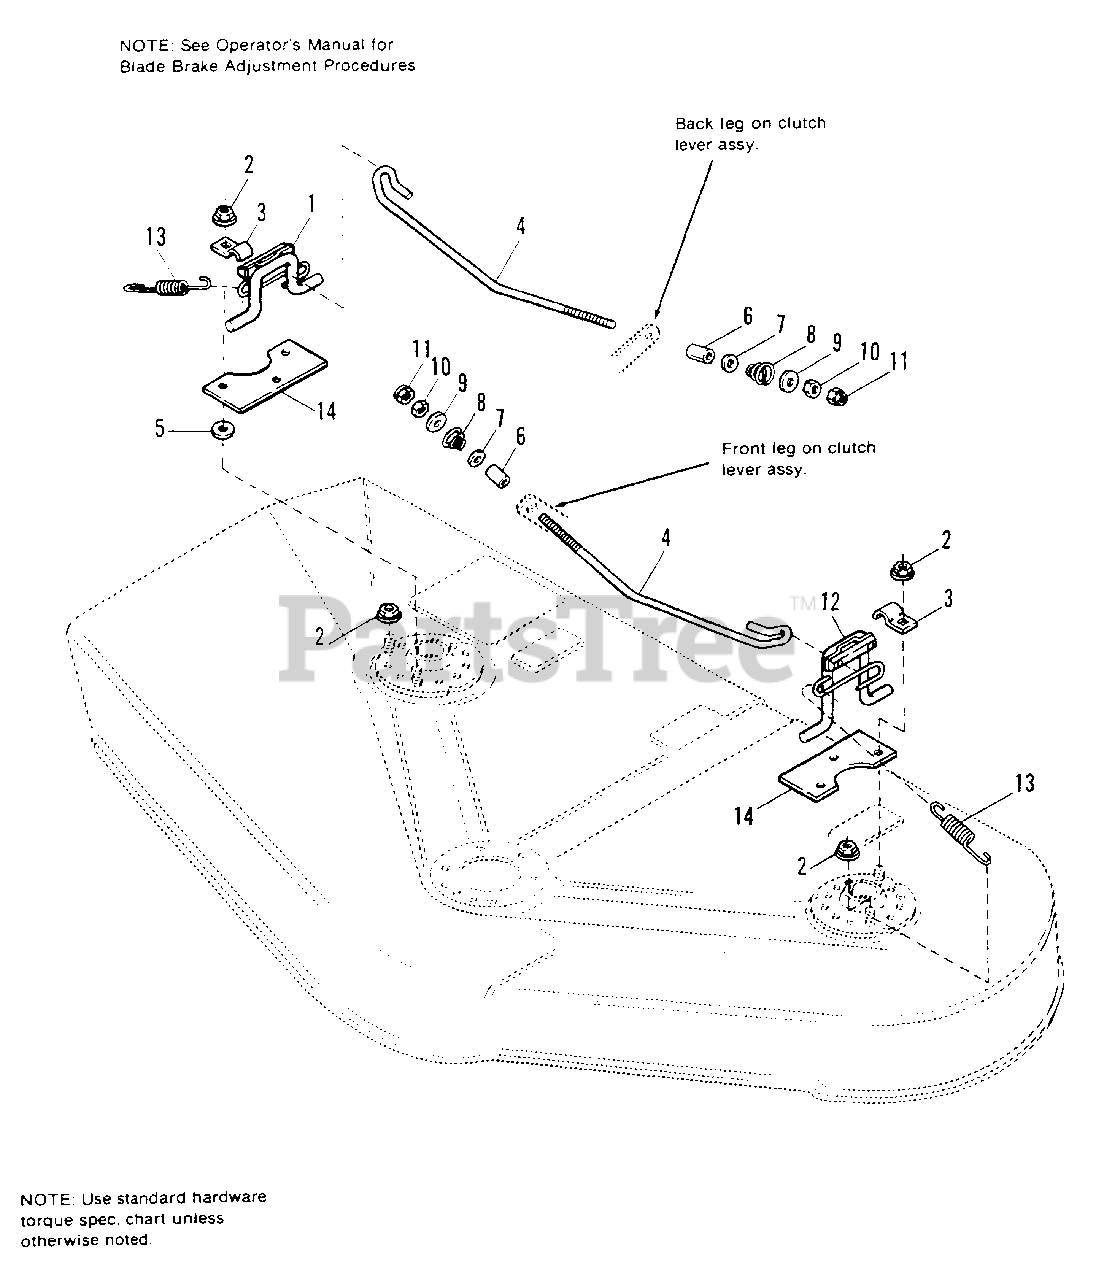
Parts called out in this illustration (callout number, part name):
1	ROD ASSY, Brake, R.H. w/Pad
2	NUT, Hex Flange Lock, 5/16-18
4	ROD Brake 42
4	ROD, Brake, 48"
5	WASHER 13/32 x 1
7	WASHER 1/4
9	WASHER, 11/32 x 1
10	NUT Hex Full 1/4-20
11	NUT, Hex Lock, Esna Light, 1/4-20
12	ROD ASSY., Brake, L.H. w/Pad
13	SPRING, Extension
